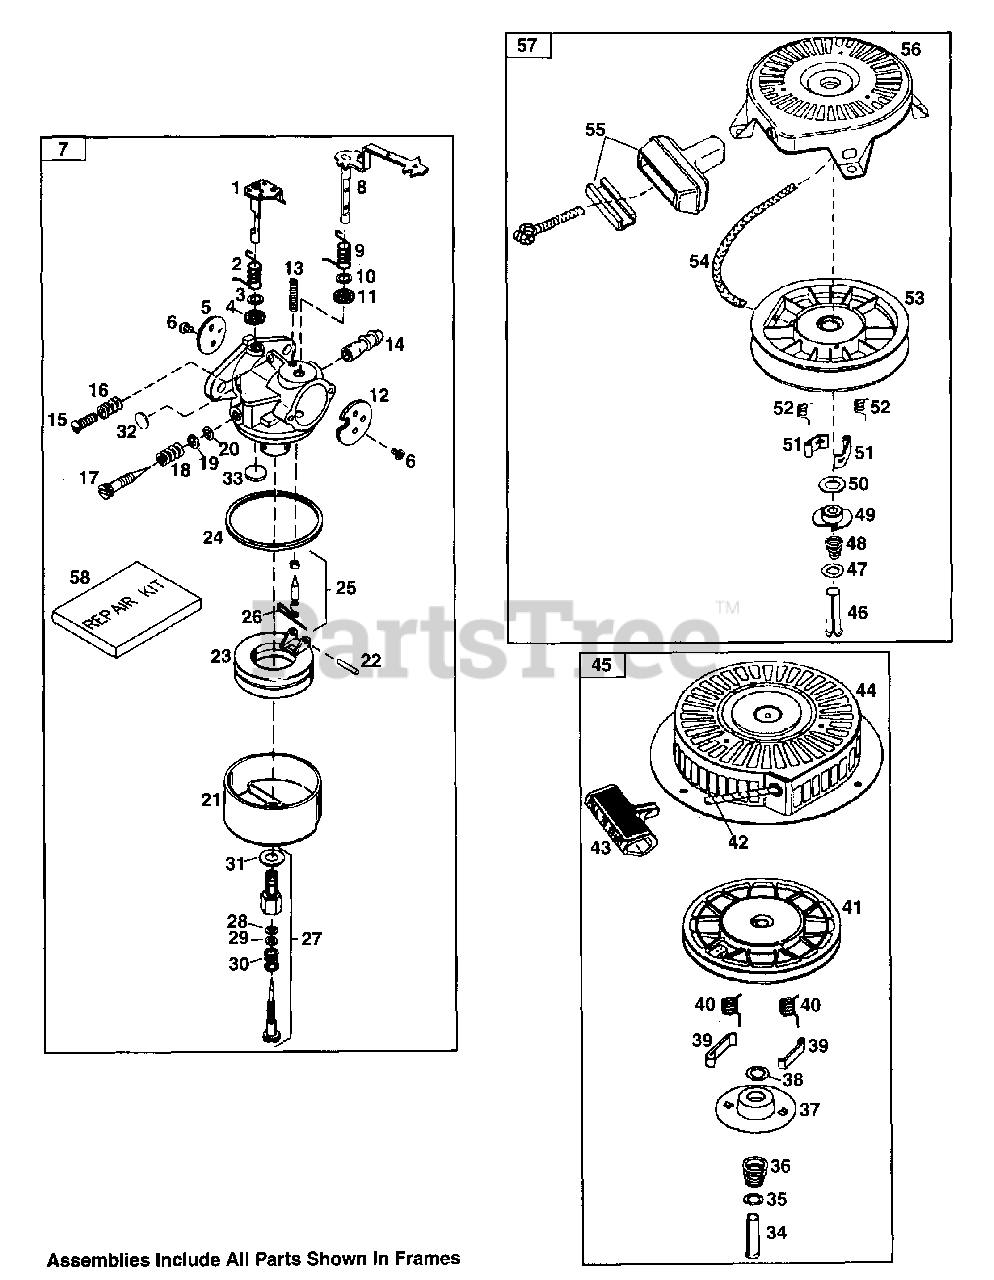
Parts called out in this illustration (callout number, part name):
1	Throttle Shaft & Lever Ass'y
2	Throttle Return Spring
3	Dust Seal Washer
4	Dust Seal (Throttle)
5	Throttle Shutter
6	Shutter Screw
7	Carburetor Ass'y
8	Choke Shaft & Lever Ass'y
9	Choke Return Spring
10	Dust Seal Washer
11	Dust Seal Choke
12	Choke Shutter
13	Choke Positioning Spring
14	Fuel Fitting
15	Throttle Crack/Idle Speed Screw
16	Tension Spring
17	Idle Mixture Screw
18	Tension Spring
19	Idle Mixture Screw Washer
20	Idle Mixture Screw "O" Ring
21	Float Bowl
22	Float Shaft
23	Float
24	Float Bowl "O" Ring
25	Inlet Needle, Seat & Clip
26	Spring Clip
27	Main Adjustment Screw Ass'y
28	High Speed Mixture Screw "O" Ring
29	High Speed Mixture Screw Washer
30	High Speed Mixture Screw Tension
31	Bowl Nut Washer
32	Welch Plug, Idle Mixture Well
33	Welch Plug, Atmospheric Vent
36	Brake Spring
39	Starter Dog
40	Dog Spring
41	Pulley & Rewind Spring Ass'y
42	Starter Housing Ass'y
43	Starter Rope (98")
44	Starter Handle
45	Rewind Starter Ass'y
48	Brake Spring
51	Starter Dog
52	Dog Spring
53	Pulley & Rewind Spring Ass'y
54	Starter Rope (114")
55	Starter Handle
56	Starter Housing Ass'y
57	Recoil Starter Ass'y
58	Carb. Repair Kit
